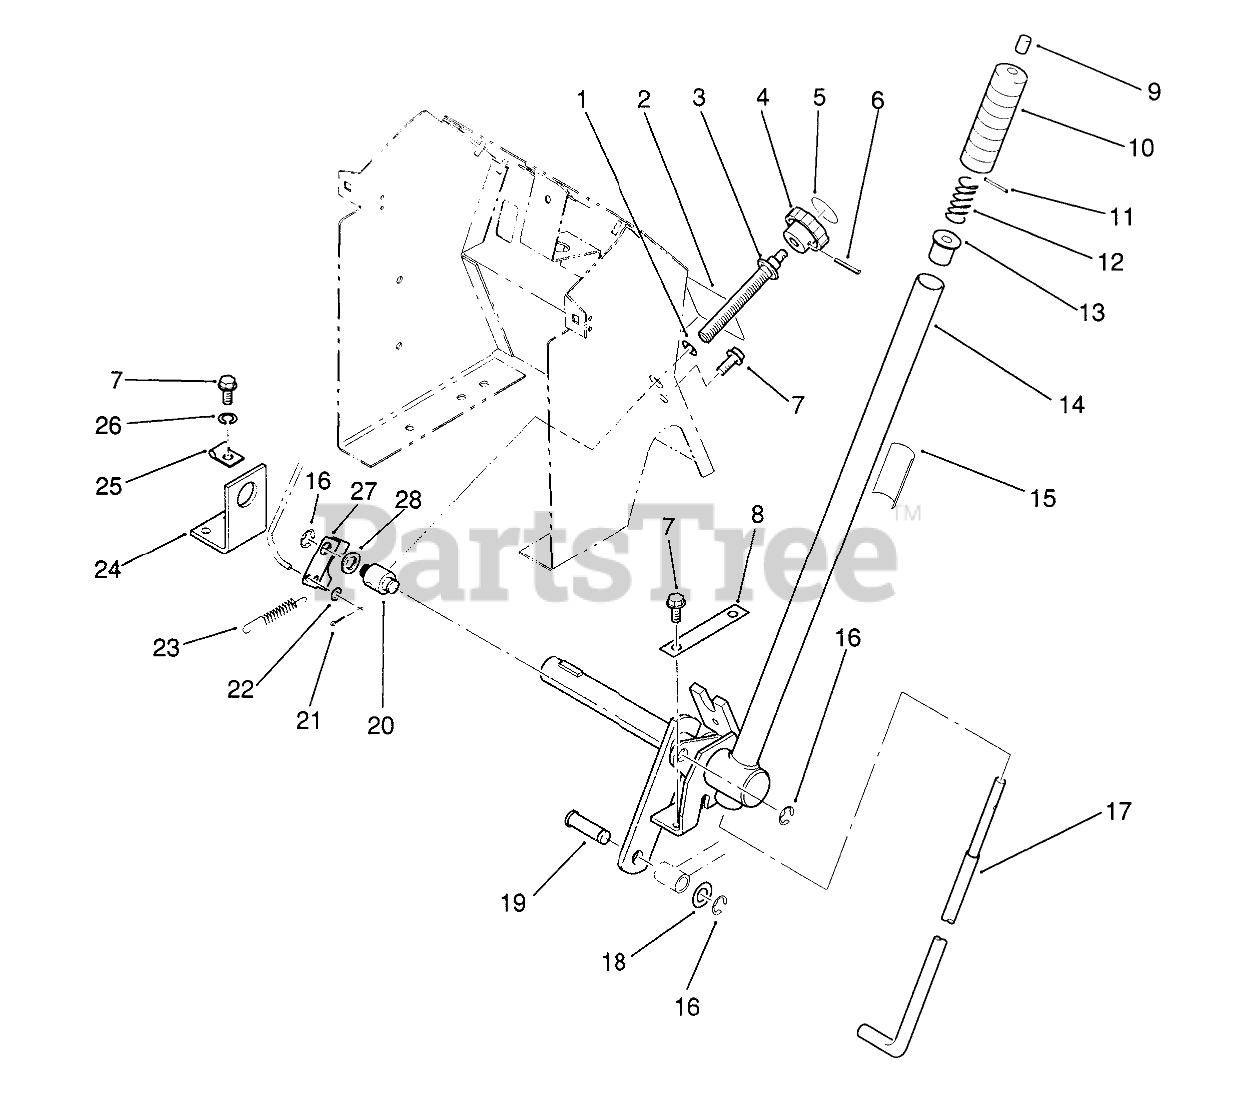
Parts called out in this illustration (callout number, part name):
1	WASHER
2	DECAL-LWR HOODSTAND
3	ROD B
5	DECAL-HEIGHT KNOB
6	PIN-SPIROL
7	Screw
8	Plate
9	CAP-ROD, PLUNGER
10	HANDGRIP
11	PIN-SPIROL
12	SPRING-COMPRESSION
13	RETAINER-SPRING
14	Handle
15	DECAL-LIFT
16	E Ring
17	ROD-LATCH LIFT
18	Washer
20	TRUNNION
21	Pin-Cotter
22	Washer
23	SPRING-EXTENSION
24	BRACKET B
25	THROTTLE CONTROL CLP
26	Washer-Lock
27	PLATE B
28	Washer
